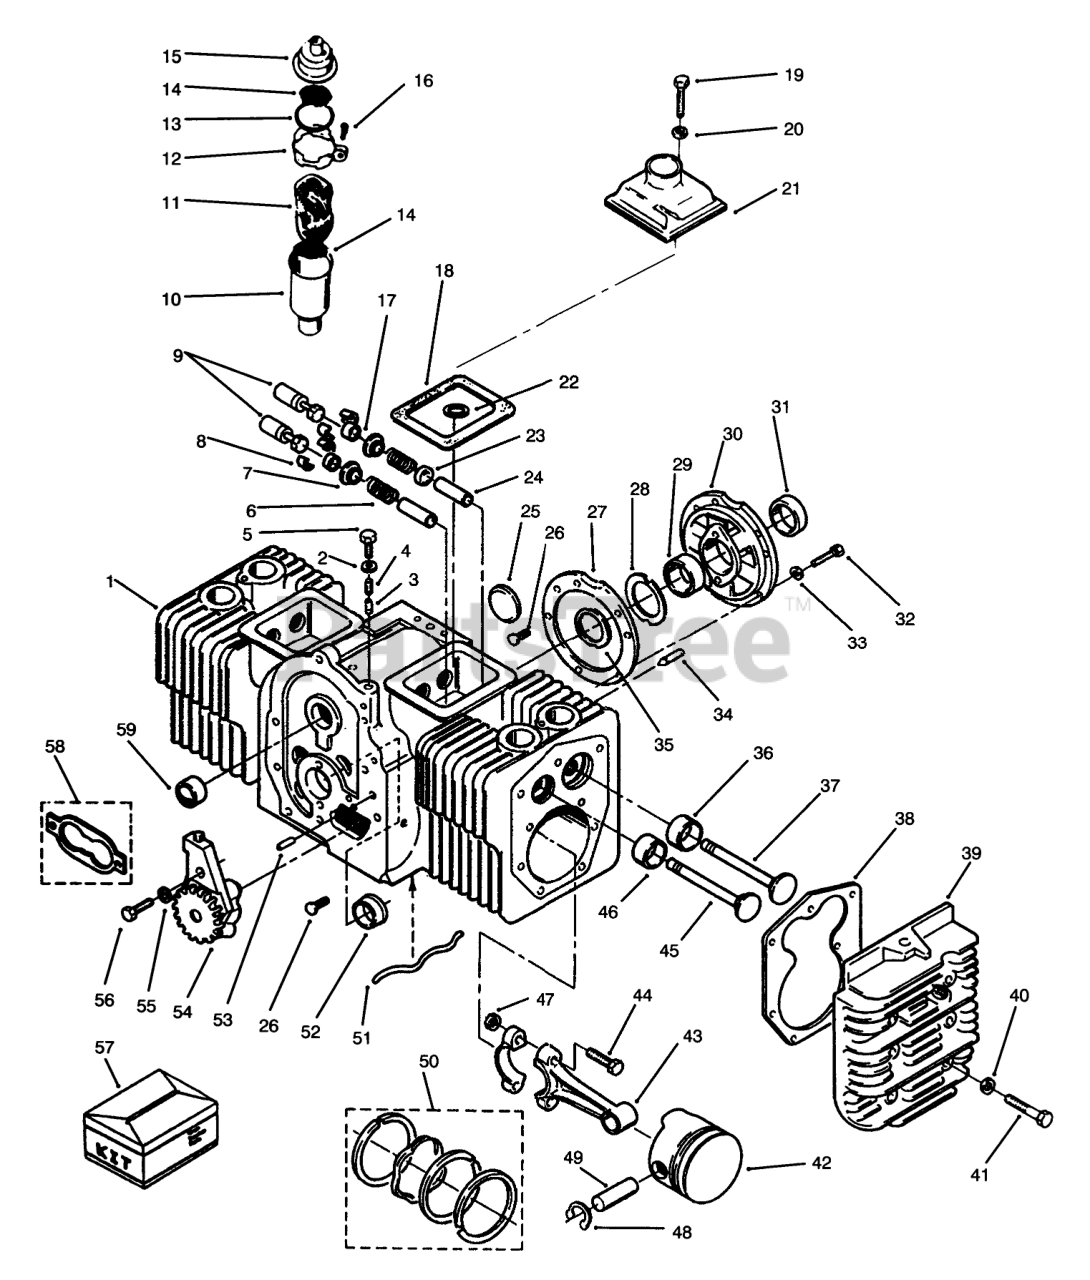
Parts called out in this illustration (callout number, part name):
1	CYLINDER BLOCK
2	WASHER
3	PLUNGER
4	SPRING
5	SCREW-HH
6	Spring
7	Washer
8	VALVE SPRING LOCK
9	Tappet-Valve
9	TAPPET
9	TAPPET .002 OS
10	TUBE-BREATHER
11	FILTER
12	Clamp
13	SEAL - O-RING
14	SCREEN-BREATHER TUBE
15	BREATHER-CAP AND VALVE
16	SCREW-TAPPING, ROUND HEAD
17	VALVE CAP
18	GASKET
19	HHCS 1/4-20 X 1 3/4
20	WASHER
21	VALVE-COVER L.H.
22	WASHER-FLAT
23	VALVE STEM SEAL
24	Guide-ExhaustValve
24	Guide-Intake Valve
26	PIN-DRIVE
27	GASKET
29	BEARING KIT (STANDARD SLEEVE)
29	BEARING-CRANKSHAFT (.002)
29	BEARING KIT (.010)
29	BEARING-CRANKSHAFT (.020)
29	BEARING-CRANKSHAFT (.030)
30	PLATE-BEARING, REAR
32	HEX HD CAPSCREW
33	WASHER-LOCK
33	WASHER-FLAT
34	SCREW-SET
35	WASHER
36	Insert-Valve Seat, Intake
36	STD INSERT
36	INSERT .010
37	INTAKE VALVE
38	GASKET
39	HOUSING CYL RH
39	CYL RS HEAD
39	Side-Left
40	WASHER
41	Screw-HH
42	STD PISTON KIT
42	PISTON .010
42	PISTON .020
42	PISTON .030
43	CONNECTING ROD W/NUT
45	EXHAUST VALVE
46	Insert-Valve Seat, Exhaust
46	STD INSERT
46	INSERT .002
46	INSERT .005
46	INSERT .010
46	.025" Oversize
48	Piston Pin
49	Pin-Piston
50	Kit-Ring, Piston
50	RING/PISTON KIT
50	RING/PISTON KIT .050
50	RING/PISTON KIT .010
50	RING/PISTON KIT .020
50	RING/PISTON KIT .030
51	OIL TUBE
52	Bearing-Crankshaft, Front, Flanged
52	KIT-BEARING, SLEEVE
52	BEARING-CRANKSHAFT
52	BEARING KIT (.010)
53	PIN-GEAR COVER
55	WASHER-FLAT
56	SCREW - CAP HEX HEAD
57	Kit-Gasket
57	ENGINE GASKET KIT
57	GASKET KIT
58	GASKET KIT
59	SLEEVE-BEARING
